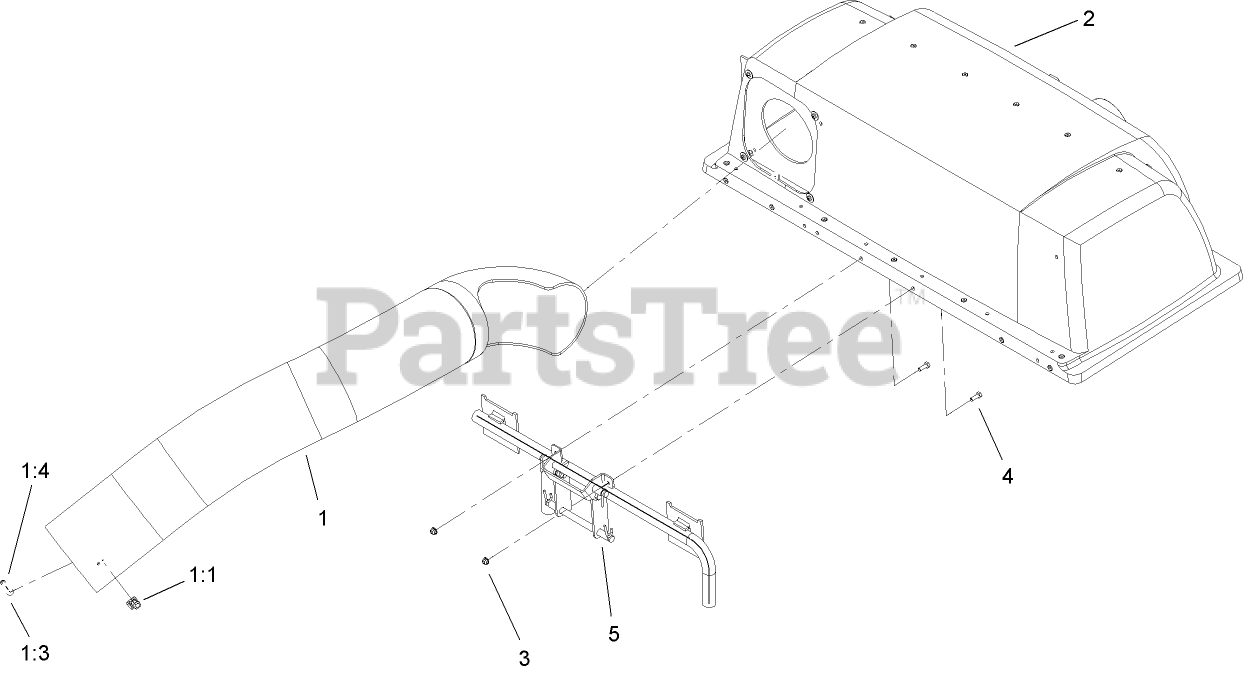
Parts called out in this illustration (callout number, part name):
1	UPPER TUBE ASM
1:1	LATCH-KEEPER
1:3	SCREW-PPH
1:4	WASHER-FLAT
2	HOOD ASM
3	NUT-HF
4	SCREW-HH
5	BAGGER MOUNT ASM
